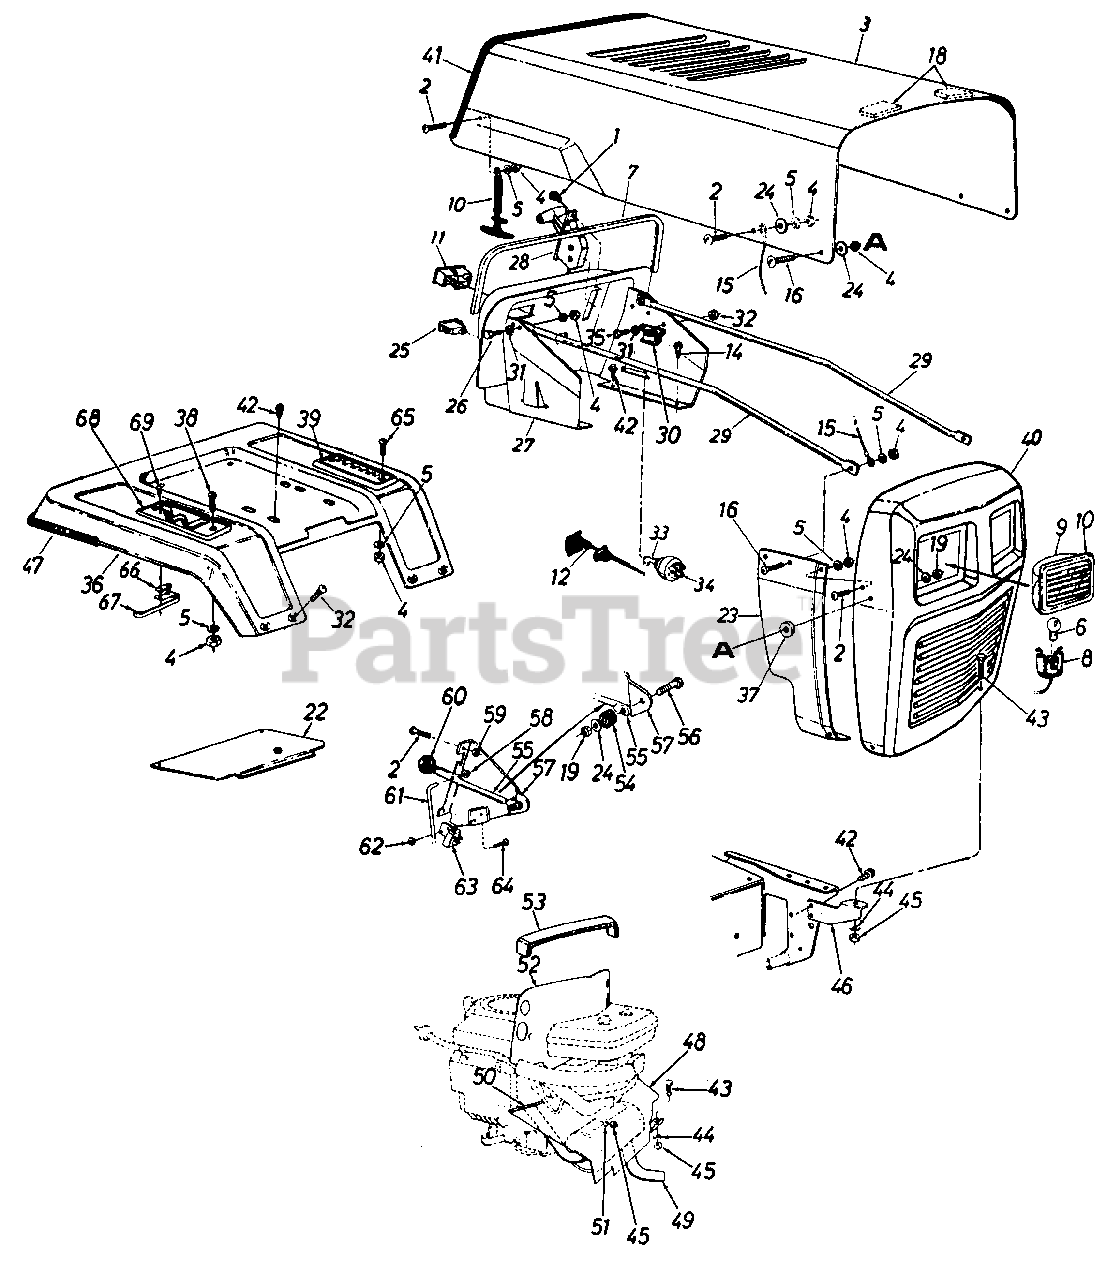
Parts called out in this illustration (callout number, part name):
1	Truss Mach. AB-Tap Scr. #10 x 5" Lg.
2	Truss Mach. Scr. 1/4-20 x .5" Lg.
5	L-Wash. 1/4" I.D.
6	Lamp
7	Trim Strip 31" Lg.
8	Socket
9	Headlight Housing
10	Lens
11	Ammeter
12	Choke Control 46" Lg.
14	Hex Tap Scr. #10 x .5" Lg.
15	Hood Stop
16	Truss Mach. Scr. 1/4-20 x .75" Lg.
18	Foam Strip
19	Hex Patch L-Nut 1/4-20 Thd.
22	Transmission Cover
25	Light Switch
26	Truss Mach. Scr. 1/4-20 Thd.
27	Dash Panel Ass'y.
28	Throttle Control Box Ass'y.
29	Grille Support Rod
30	Solenoid
31	Ext. L-Wash. 1/4" I.D.
32	Carriage Bolt 1/4-20 x .5" Lg.
33	Ignition Key
34	Ignition Switch
35	Hex Bolt 1/4-20 x .5" Lg.
38	Truss Mach. Scr. 1/4-20 x 1" Lg.
39	7-Speed Index Brkt.
42	Hex Wash. AB-Tap Scr. 5/16 x .75" Lg.
43	Hex Bolt 5/16-18 x .75" L.'l.
44	L-Wash. 5/16" I.D.
45	Hex Nut 5/16-18 Thd.
46	Grille Mtg. Bracket-R.H.
47	Trim Strip 81" Lg.
48	Front Heat Shield
49	Muffler
50	Trim Strip 12" Lg.
51	Spec. L-Wash. 5/16" I.D.
52	Top Heat Shield
53	PVC Foam
54	Rubber Washer
55	PTO Lever
56	Hex Bolt 1/4-20 x 1.25" Lg.
57	Deck Clutch Control Brkt.
58	Push Cap
59	Hex Sems Nut 1/4-20 Thd.
60	Knob-Blade Clutch
61	Deck Control Rod
62	Hex Nut #10-24 Thd.
63	Safety Switch
64	Truss Mach. Scr. #10-24 x 5" Lg.
65	Truss Mach. Scr. 1/4-20 x 1" Lg.
66	Insulator Nut Plate
67	Reverse Safety Switch
68	Forward/Reverse Index Brkt.
69	Hex Wash. Hd. AB-Tap Scr. #8 x .5" Lg.
